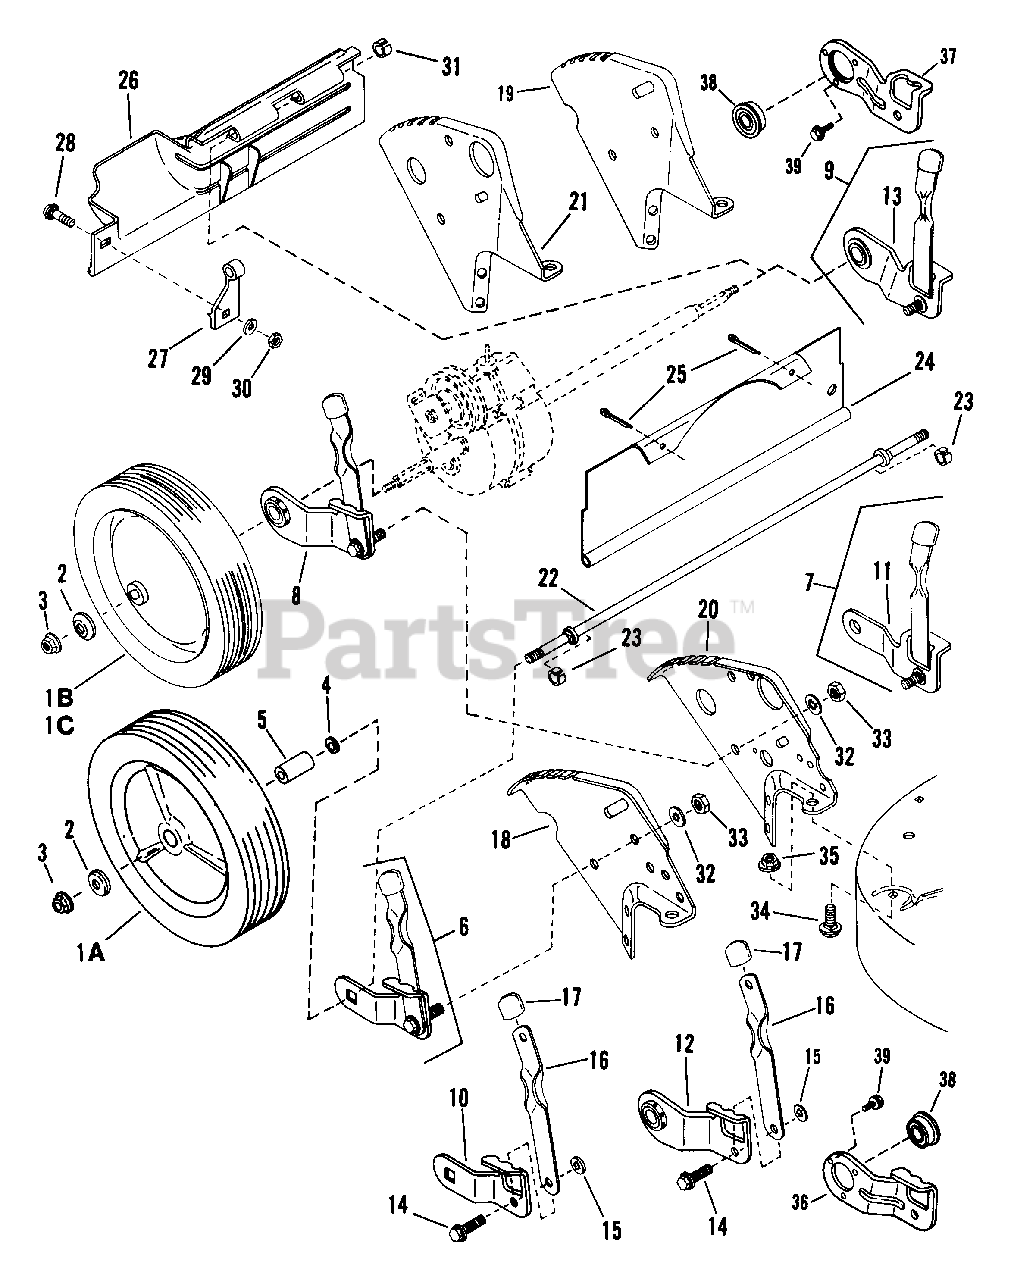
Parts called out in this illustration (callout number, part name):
1A	WHEEL, 9 x 1.75 Plastic Rim
1B	WHEEL, 9 x 1.75 Steel Rim
1C	WHEEL, 9 x 1.95
2	HUB-CAP (Self-Propelled Models)
3	NUT, 7/16-20 Hex Center Lock
4	WASHER, Steel
5	BUSHING, Axle
6	WHEELARM ASSEMBLY
7	WHEEL ARM ASSEMBLY
8	ASSEMBLY, Wheel Arm (Rear Right "P" Models)
9	ASSEMBLY, Wheel Arm (Rear Left "P" Models)
10	ARM (Square Axle End)
11	ARM (Round Axle End)
12	ARM & BEARING ASSEMBLY, Rear Right "P" Models
13	ARM & BEARING ASSEMBLY, Rear Left "P" Models
14	BOLT, 5/16-18 x 1 Shoulder
15	RETAINER, 5/16 Bolt
16	LATCH, Height Adjusting
17	GRIP, Latch
18	BRACKET, Right Rear Wheel
19	BRACKET, Left Rear Wheel
20	BRACKET, Right Rear Wheel
21	BRACKET, Left Rear Wheel
22	AXLE,
23	RING
24	GUARD, Rear Foot
25	COTTER PIN, 1/8 x 1-1/2"
26	GUARD, Rear Foot (Self-prop. "P" Models)
27	SUPPORT, Foot Guard
28	BOLT, 1/4-20 x 1/2 Short Neck Carriage Gr.5
29	WASHER, 1/4 Int. Tooth Lock
30	NUT, 1/4-20 Hex
31	RING
32	WASHER, 5/16 Int. Tooth Lock
33	NUT, 5/16-18 Hex
34	BOLT, 5/16-18 x 1/2 Short Neck Carriage
35	NUT,5/16-18 Hex Flange Lock
36	ARM, Wheel Rear Right "P" Models
37	ARM, Wheel Rear Left "P" Models
38	BEARING
39	SCREW, #10-32 x 1/4" Self-Tapping
